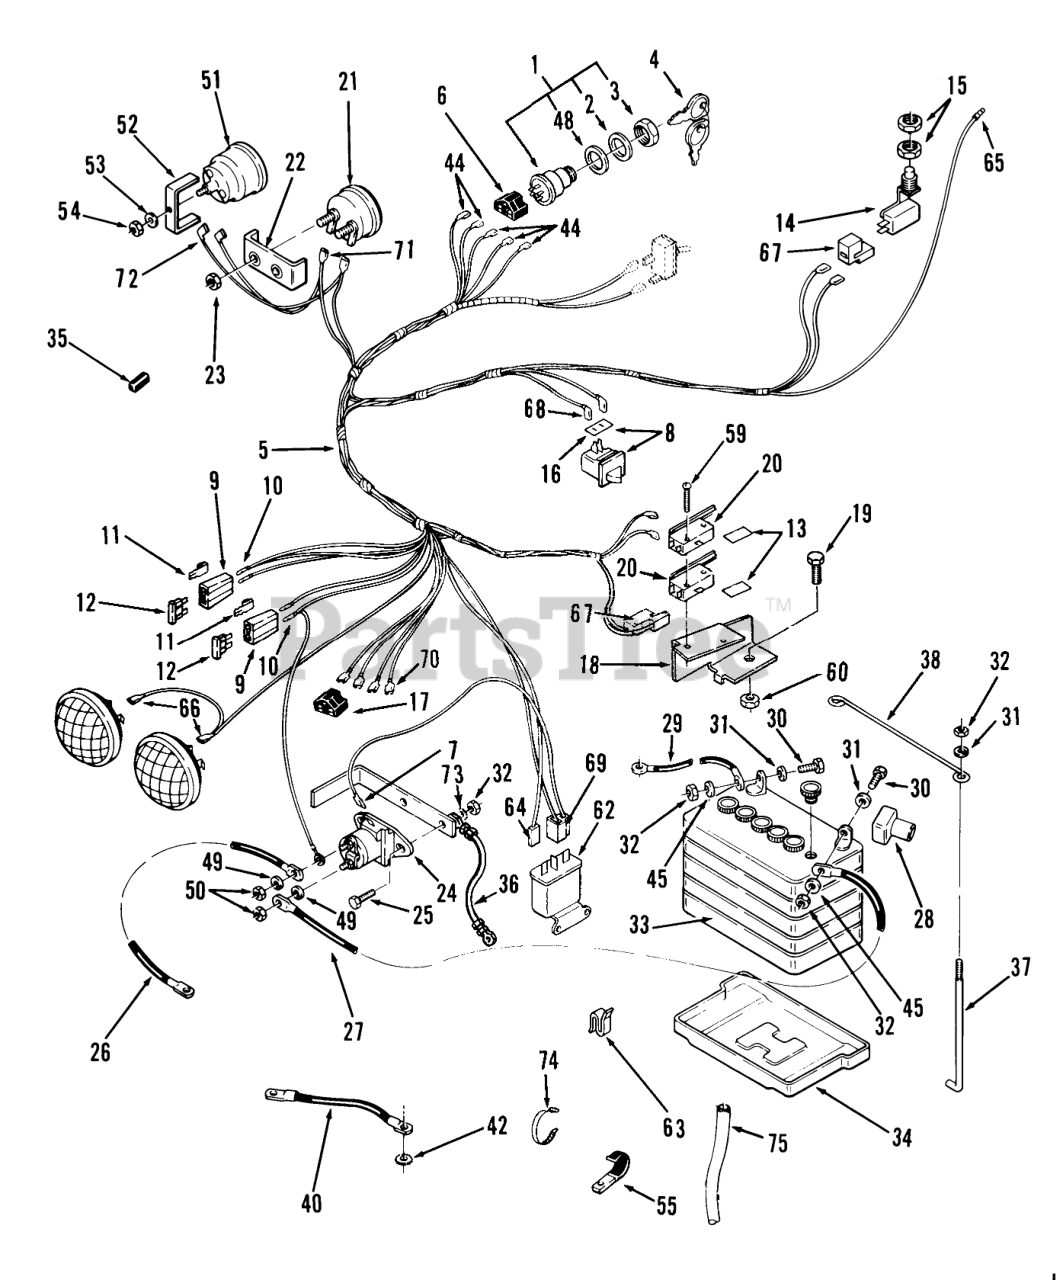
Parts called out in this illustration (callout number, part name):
1	Ignition Switch Ass-y
1	IGNITION SWITCH ASM
2	LOCKWASHER
4	Ignition Key
4	KEY PADDED
5	Wiring Harness Assembly 310, 312, 414
5	HARNESS-WIRE
6	CONNECTOR-5 WAY-SERV
7	TERMINAL 10
8	SWITCH ASM (SERVICE)
9	AUTO-FUSEBLOCK TERM
10	TERMINAL FUSE
12	FUSE-BLADE, 15 AMP
12	FUSE-BLADE, 25 AMP
13	BARRIER - SWITCH
14	Seat Switch
15	NUT-HEX, SPECIAL
16	SHIELD-DIRT SPST
17	5-CONTACT CONN BODY
18	Support-Switch
19	Bolt
20	SWITCH
21	Voltmeter (w/109650)
22	CLAMP MOUNTING
23	HEX NUT 10-32 E.S.
24	Solenoid
25	Screw
26	ASSY WIRE
27	CABLE-BLACK
28	Boot
29	ASSY WIRE
30	Bolt
32	Nut
33	Battery
34	TRAY BATTERY
35	GRIP
35	VALVE LEVER GRIP
36	GROUND-WIRE
38	HOLDDOWN-BATTERY
40	WIRE GROUND
42	Washer-Lock
44	Terminal
45	Washer
48	Washer
49	Washer
50	Nut
51	GAUGE-HOURMETER
52	BRKT-GAUGE MOUNTING
53	Lockwasher
54	Hex Nut
55	CLIP
59	Screw
60	NUT HEX 4-40 ELAST
62	Relay
63	CLIP-CABLE
64	TERMINAL 10
65	Sur-Plug
67	CONNECTOR BODY
68	Terminal
69	CONNECTOR BODY B
70	Connector Part of 5
71	TERMINAL-TAB RCPT
72	Terminal Part of 5
73	LOCKWASHER
74	PLASTIC TIE
75	TUBE-BATTERY DRAIN
